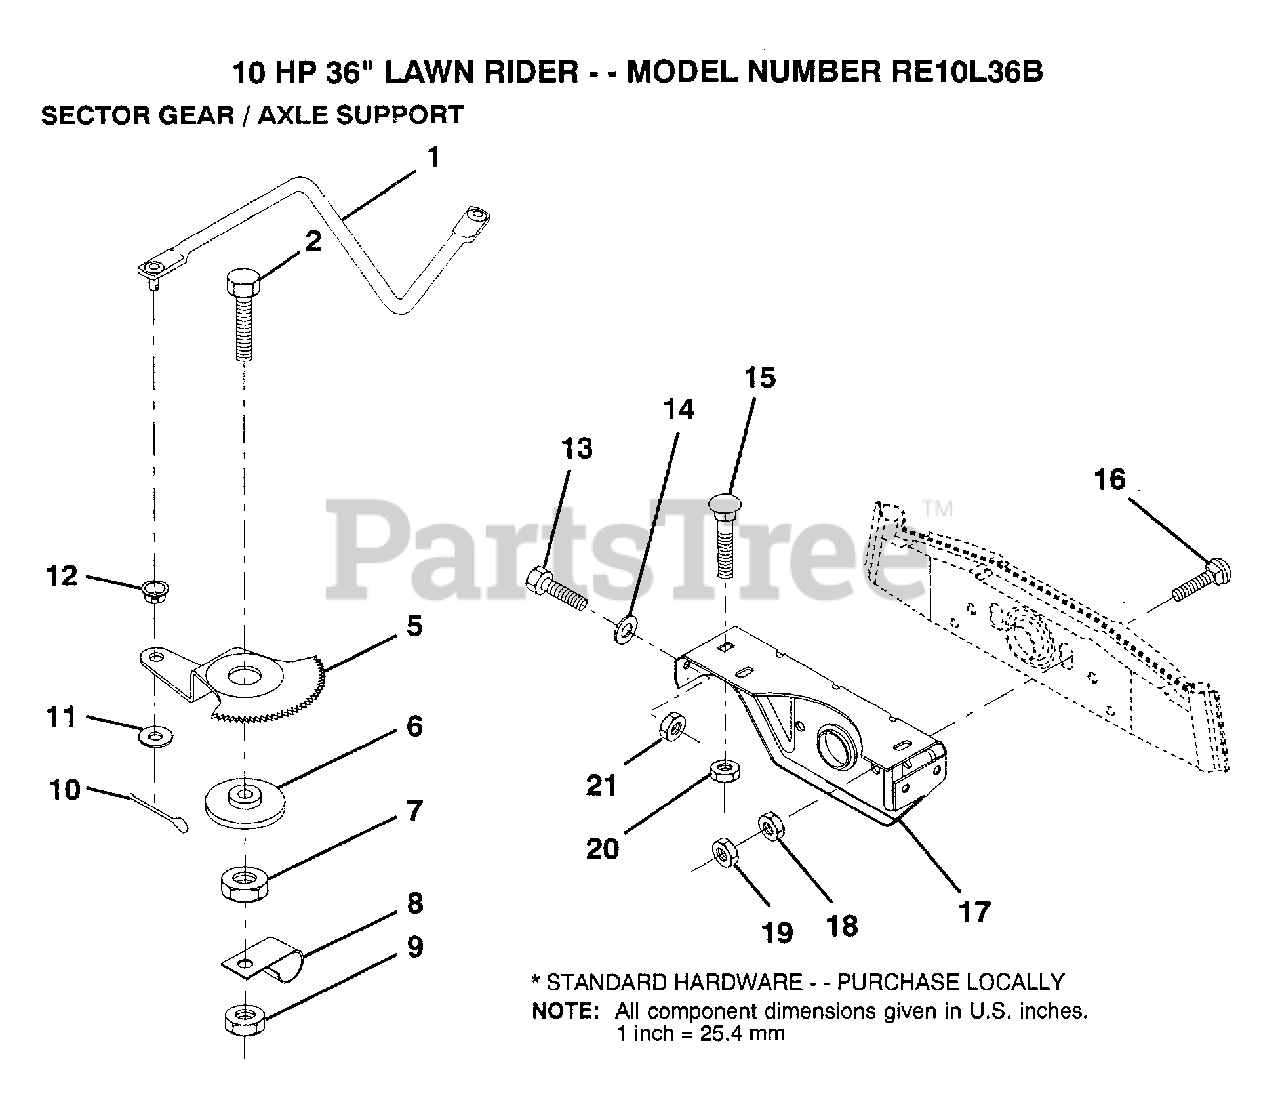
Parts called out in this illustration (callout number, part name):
2	"BOLT,HEX"
5	GEAR SECTOR
6	BUSHING
7	NUT
8	CLIP INSULATOR
9	NUT LTV
10	COTTER PIN
11	WASHER
12	BUSHING.DRAGLINK
13	BOLT
14	WASHER
15	BOLT
16	BOLT
17	"SUPT,FRT AXLE"
18	NUT.HEX.3/8-16UNC
19	LOCKNUT
